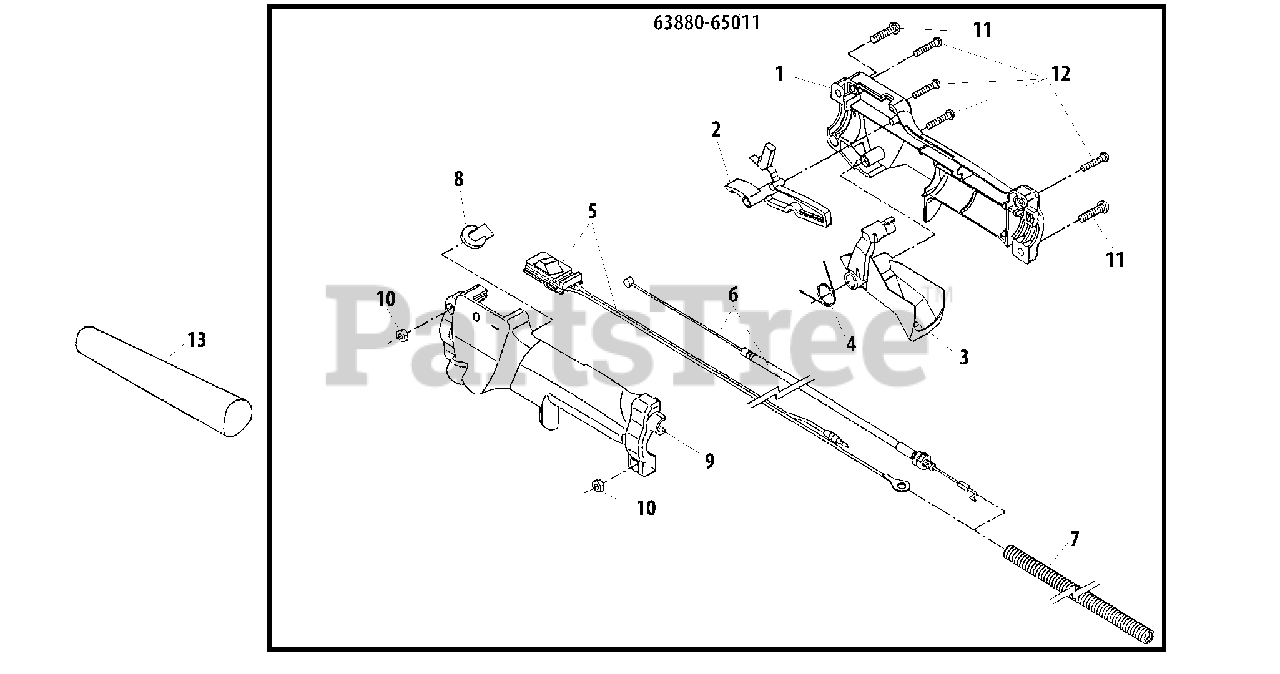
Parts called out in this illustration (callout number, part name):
1	HANDLE, CONTROL - RIGHT
2	LEVER, LOCK
3	LEVER
4	SPRING
5	SWITCH, IGNITION
6	CABLE, THROTTLE
7	TUBE
8	PLUG
9	HANDLE, CONTROL - LEFT
10	NUT - 5
11	SCREW - 5X20
12	SCREW - 4X20 -- TAPPING
13	COLLAR
63880-65011	THROTTLE LEVER ASSY
